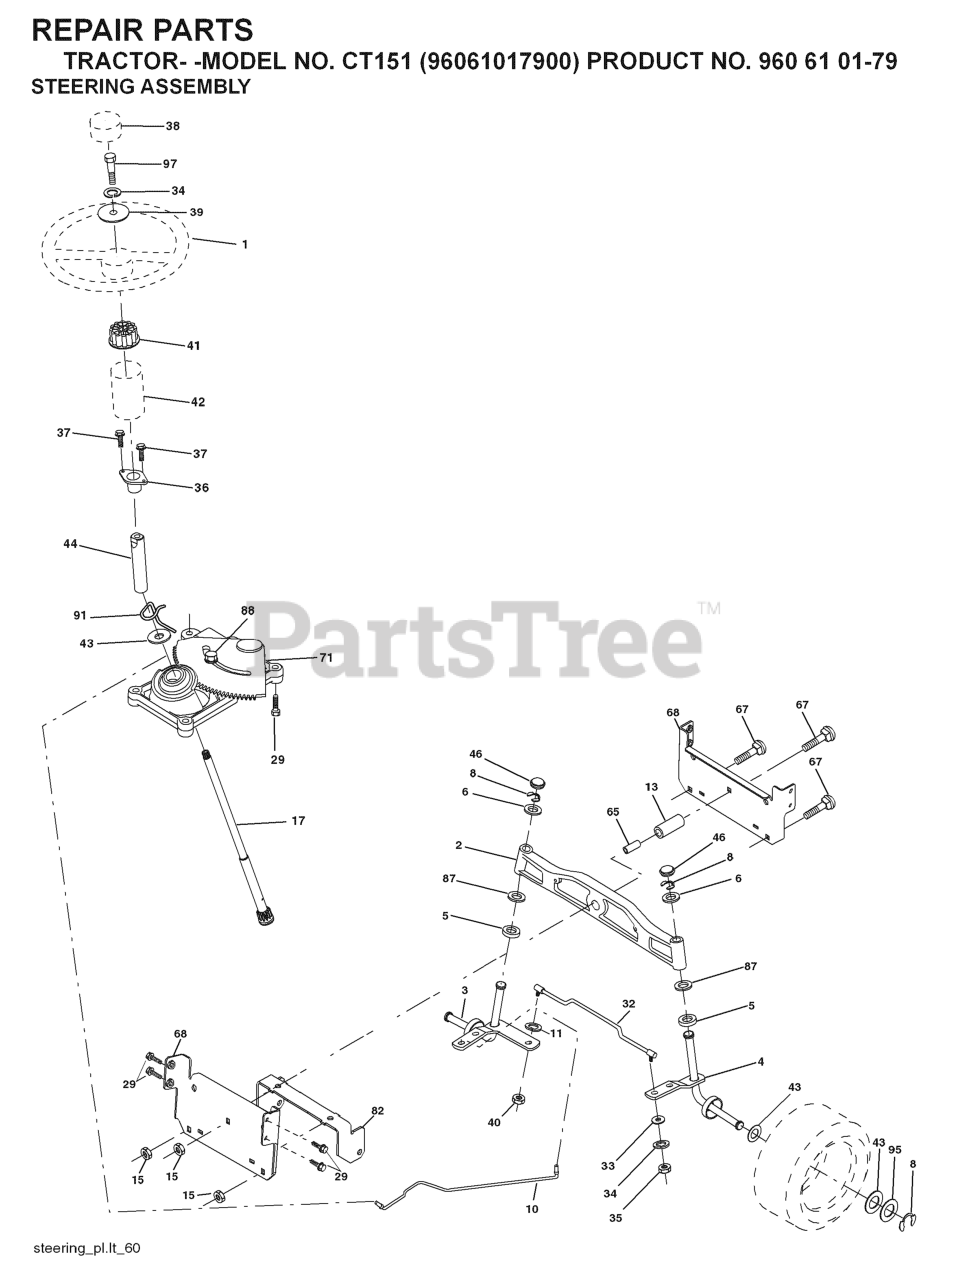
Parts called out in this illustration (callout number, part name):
3	NUT FLANGE - M6
8	SCREW EHHFM
9	SCREW
10	NUT FLANGE
11	RETAINING RING
12	SCREW IHSCM.
13	WASHER BRB 8.4X17
35	REVERSE SWITCH
52	DECAL.HUSQVARNA.210MM
54	SCREW
